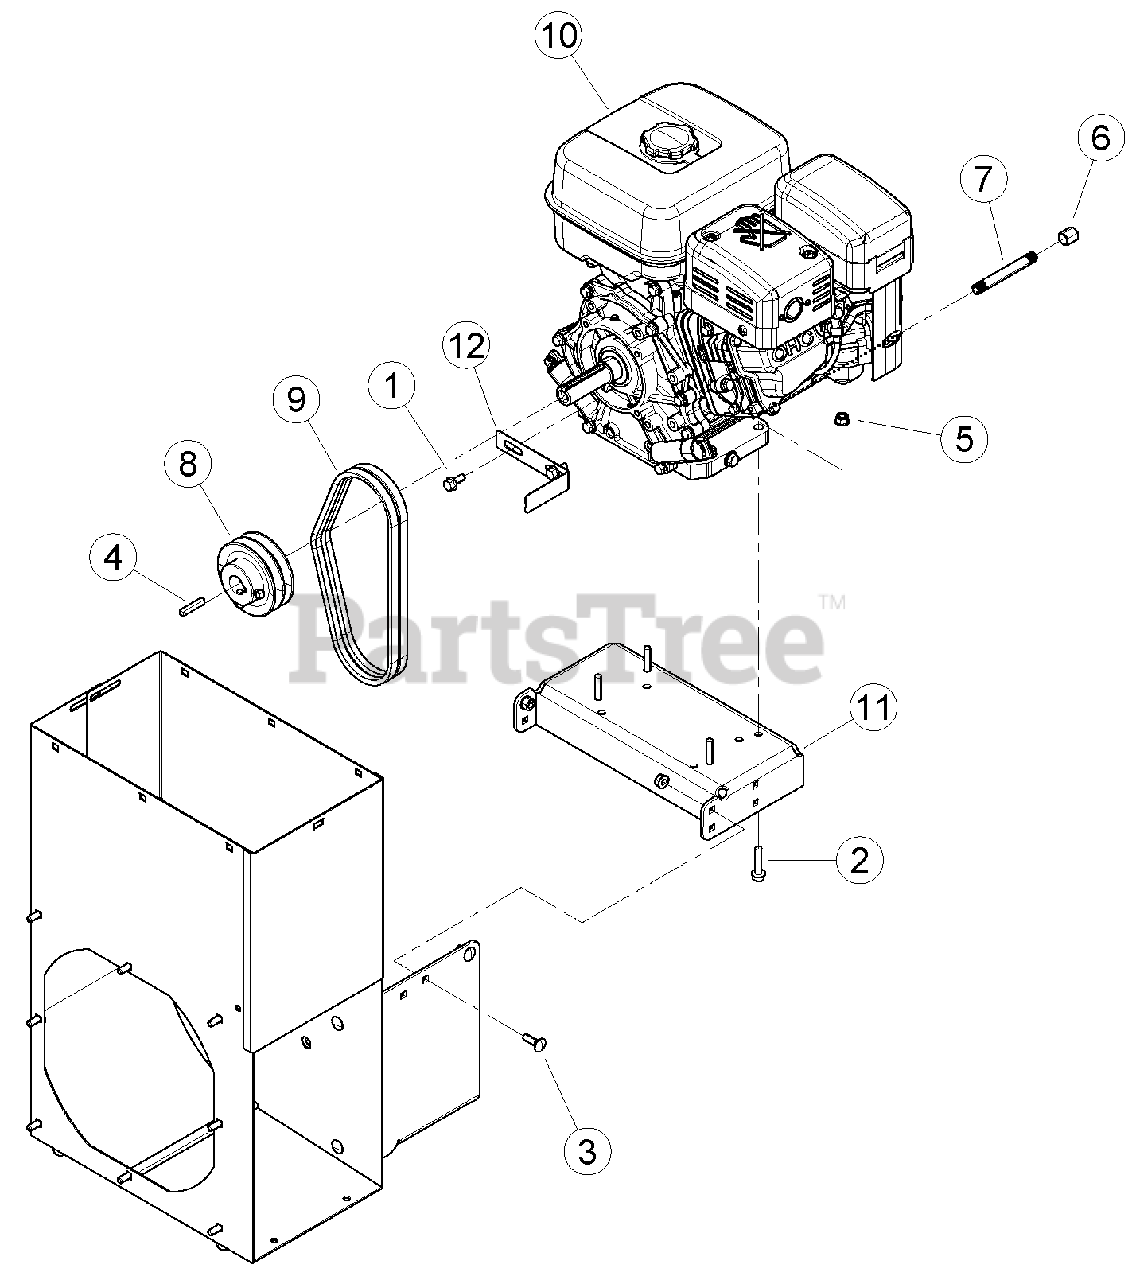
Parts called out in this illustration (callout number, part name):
1	BOLT, 5/16 X 3/4 SERR FLANGE NF
2	BOLT, 5/16 X 1-1/2 FLANGE NC
3	BOLT, 5/16 X 1" GR5 CRG ZP
4	KEY, 1/4 SQUARE X 1-1/2 LONG PLAIN
5	NUT, 5/16-18 NYLOCK-FLANGE
6	PIPE CAP, 1/4" GALV. HEX HEAD
7	PIPE NIPPLE, 1/4 X 4" GALVANIZED
8	PULLEY, 4 X 1 2A GROOVE
9	BELTS, HAH29.1 EL MATCHED SET
10	ENGINE, 342CC B+S HORIZONTAL
11	PLATE, ENGINE MOUNTING
12	GUIDE, BELT
